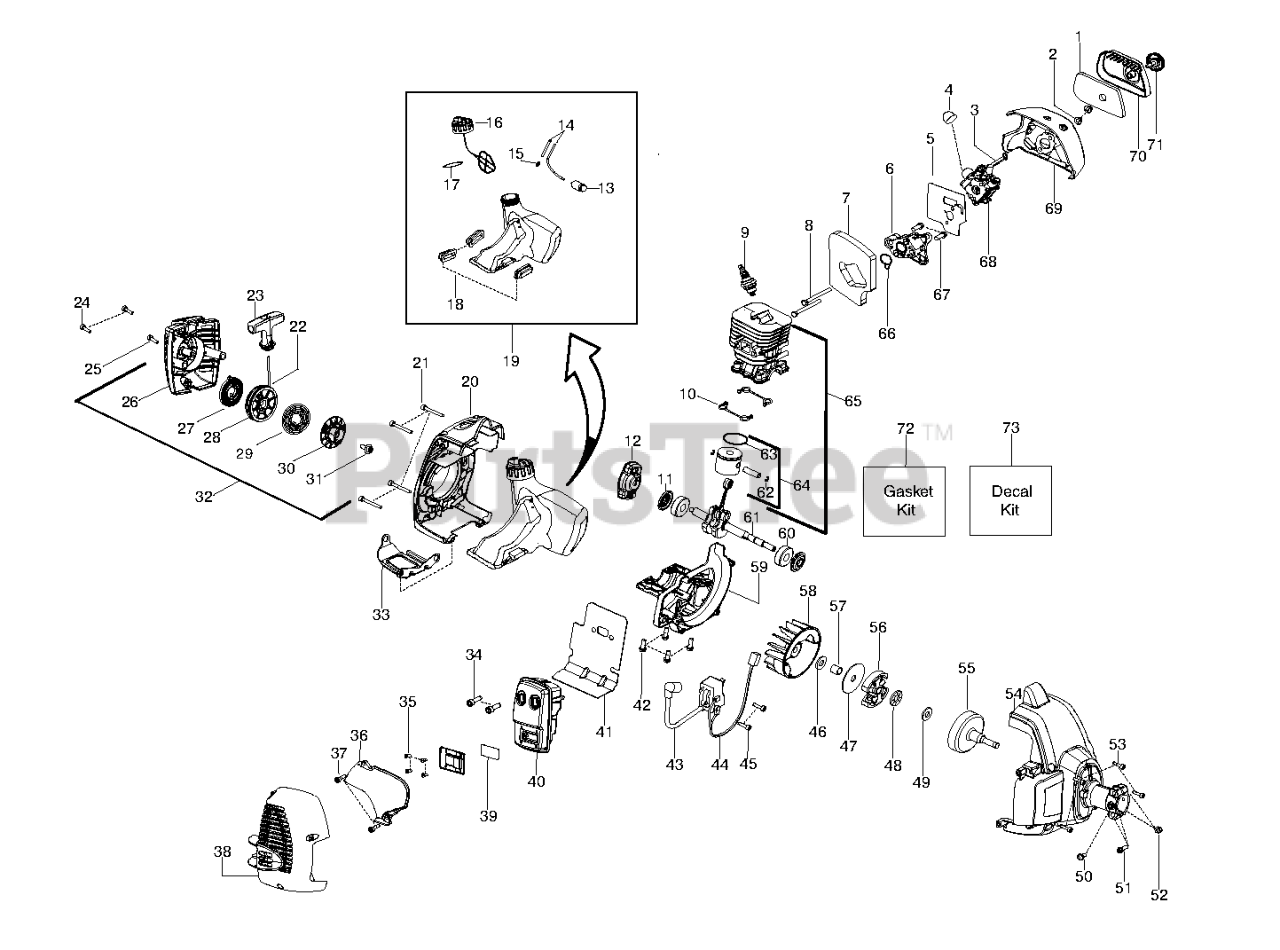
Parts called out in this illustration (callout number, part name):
1	FILTER AIRBOX
3	CHOKE LEVER
4	PURGE BULB ZAMA
5	KIT GASKET CARB 28CC
6	CARB ADAPTOR
7	KIT GASKET 28CC
8	BOLT CARB ADAPTOR
10	KIT GASKET 28CC
11	KIT GASKET 28CC
12	STARTER PAWL BRIDGE
13	FUEL PICK-UP ASSY
14	KIT-LINE(FUEL)
15	FUEL LINE FITTING
16	ASSY - FUEL CAP W/RETAINER
17	KIT GASKET 28CC
18	ISOLATOR FUEL TANK
19	KIT FUEL TANK ASSY
20	SHROUD REAR
23	HANDLE - STARTER
24	SCREW M5-0.8X30MM
25	SCREW M4 X 1.75 PT 16MM
26	STARTER HSG W/EYELET
27	KIT STARTER SPRING
28	KIT STARTER PULLEY
29	SPRING - DRIVER
30	DRIVER PULLEY
32	ASSY STARTER HSG
33	PLATE WEAR
34	BOLT MUFFLER
35	SCREW-6-19X5/16PLAST PA
36	SHIELD HEAT
37	SCREW M4 X 1.75 PT 16MM
38	KIT MUFFLER GUARD
39	KIT SPARK ARRESTOR SCREEN
40	KIT MUFFLER W/CATALYST
41	KIT GASKET 28CC
42	B0LT, C/SHAFT 36/41
43	IGNITION MODULE
44	ASSY MODULE LEAD WIRE
45	SCREW M4 X .70 TT 16MM
46	WASHER CLUTCH
47	WASHER-CLUTCH
48	BEARING THRUST
49	WASHER THRUST
50	SCREW-10-16 X 1/2, TYPE 2
51	SCREW-10-24 X 1" (UNC)
52	LOCKNUT-HEX 10-24
53	SCREW M4 X .70 TT 16MM
55	ASSY-CLUTCH DRUM
56	ASSEMBLY CLUTCH
57	SPACER FLYWHEEL
59	CRANKCASE CAST LE28
60	BEARING RADIAL BALL (6201)
61	ASSY CRANKSHAFT
62	WRIST PIN RET.
63	RING PISTON
64	KIT - PISTON
65	KIT PISTON CYL
66	KIT GASKET 28CC
67	B0LT, C/SHAFT 36/41
68	KIT CARB
69	AIRBOX BLACK
70	COVER AIR BOX
71	ASSY - AIR BOX KNOB
72	KIT GASKET 28CC
